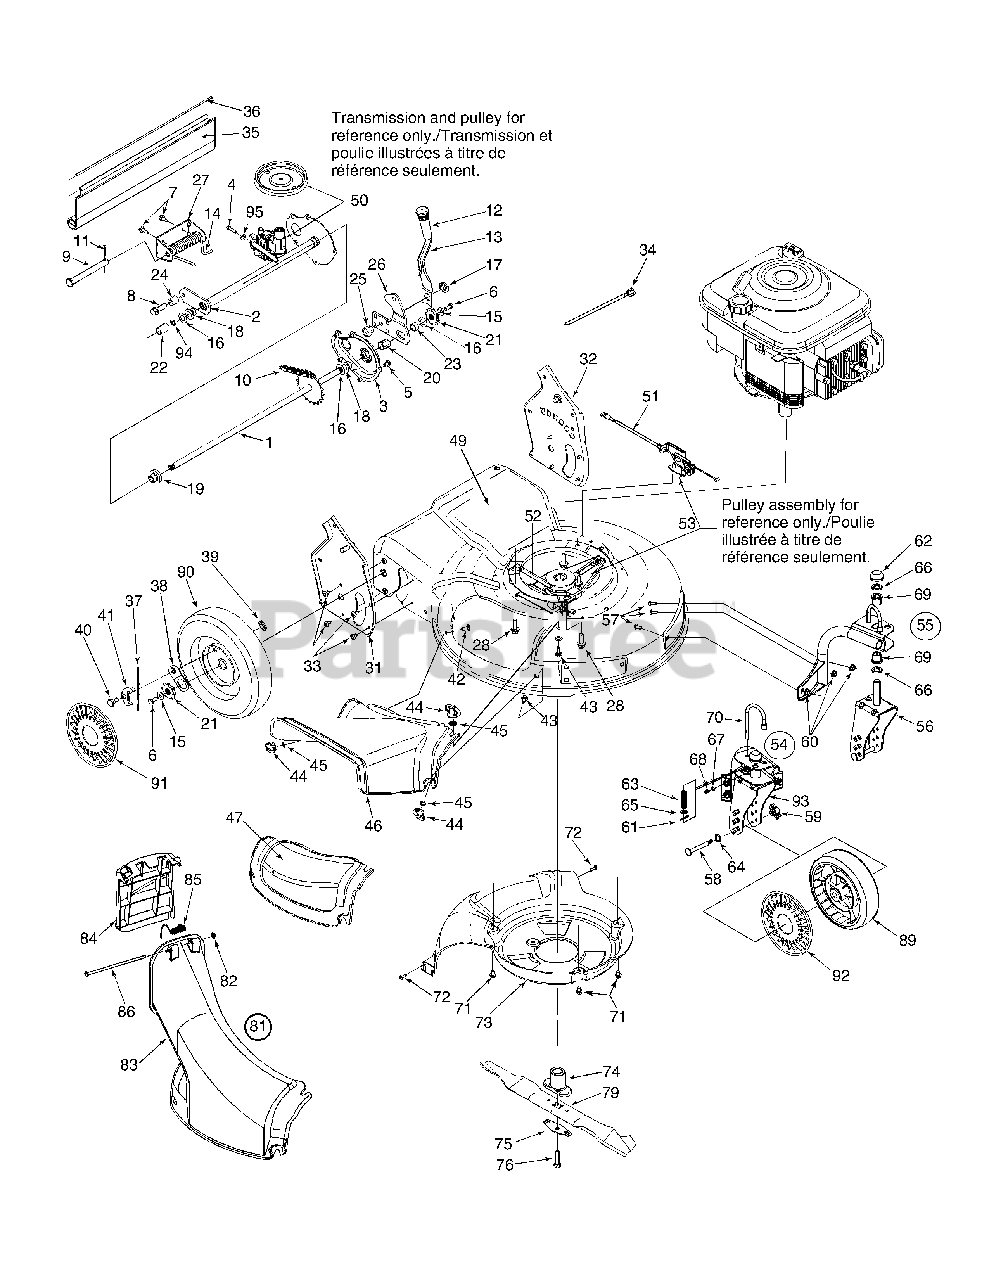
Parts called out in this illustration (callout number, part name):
1	Axle Ass’y 20T x 21.46" Lg.
2	Trans Axle Ass’y
3	Chain Cover Ass’y
4	Hex Wash HD Screw 5/16-18 x .62
5	Hex Wash HD Tapp Screw 1/4-20 x .38
6	Hex Bolt 1/4-20 x .62
7	Hex Wash Hd. Screw 1/4-20 x .625" Lg
8	TT Screw 3/8-16 x 1.25
9	Clevis Pin .5" Dia. x 4.62" Lg.
10	Chain, No. 48 End less .50 x 24 links
11	Cotter Pin
14	RH Torsion Spring
15	Cupped Wash. .25 ID x .88 OD x .062
16	Washer, Flat .505 ID x 1.0
17	Shoulder Nut .625 DIA. x .165
18	Flange Bearing .506 ID
19	Hex Flange Bearing
20	Hex Sleeve Bearing .504 x .830 Lg.
21	Ratchet Wheel
22	Spacer .55 ID x .75
23	Sleeve .511 ID x .70 OD x .37" LG.
24	Spacer .38 x .625" Lg.
25	Shoulder Spacer .385 ID x .715" Lg.
35	Rear Flap 17.25" Lg.
37	Spring Nylon
38	Pawl Plate
39	Toplock Flat Weldnut 1/4-20
40	Shoulder Screw .340 x .285: 1/4-20
42	Carriage Bolt 1/4-20 x .62
43	Carriage Bolt 1/4-10 x .75
44	Wing Nut
45	Flat Washer .260 x .720 x .060
47	Mulching Baffle
50	Transmission Ass’y
51	SP Cable 51.0" Lg.
52	V-Belt 3/8 x 39.24" Lg.
53	Pulley & Actuator (6 speed)
57	Carriage Bolt 5/16 x 18 x .62" Lg.
59	Wing Nut
60	Hex Flange L-Nut 5/16-18 Gr. F
61	Int. Cotter Pin 5/16 DIA
62	Push Cap 5/8" Dia Rod
63	Compression Spring
64	Spring Washer .530 ID
65	Flat Washer .344 ID x .625 OD x .063
66	Flat Washer .63 ID x .12 OD x .12
67	Flat Washer .203 ID x .406 OD x .040
68	Grease Fitting
69	Flange Bearing .631 ID
71	Hex Wash HD Tapp Screw 1/4-20 x .38
72	Screw 1/4-15 X .75
73	Baffle
74	Blade Adapter (w/star)
75	Bell Blade Support
76	Hex Bolt 3/8-24 x 2.00 Gr. 8 Spe cial
77	Wave Washer .51" ID
79	Blade 21" (w/star)
81	Chute Assembly
82	Push Cap .188 Rod
84	Chute Door
85	Torsion Spring
89	Front Wheel Ass’y 7 x 2 (Link/Blk/BB)
90	Rear Wheel Ass’y 9 x 2.125 (Drive/Zag/Blk)
91	Hub Cap -Grey
92	Hub Cap -Grey (Front, w/hole)
